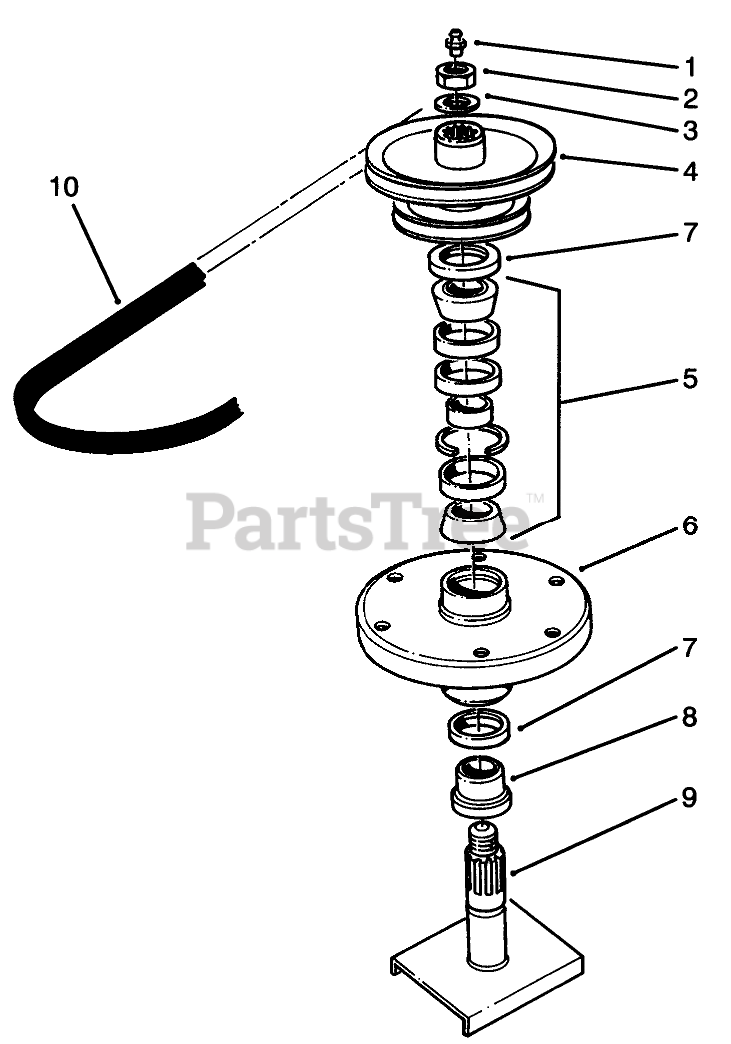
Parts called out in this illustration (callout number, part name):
1	FITTING-GREASE
2	NUT-HEX
3	WASHER
4	PULLEY AND HUB ASM
5	BEARING ASM
6	HOUSING-SPINDLE
7	SEAL-OIL
8	SPACER
9	Shaft-Spindle
10	V-BELT, DRIVE
